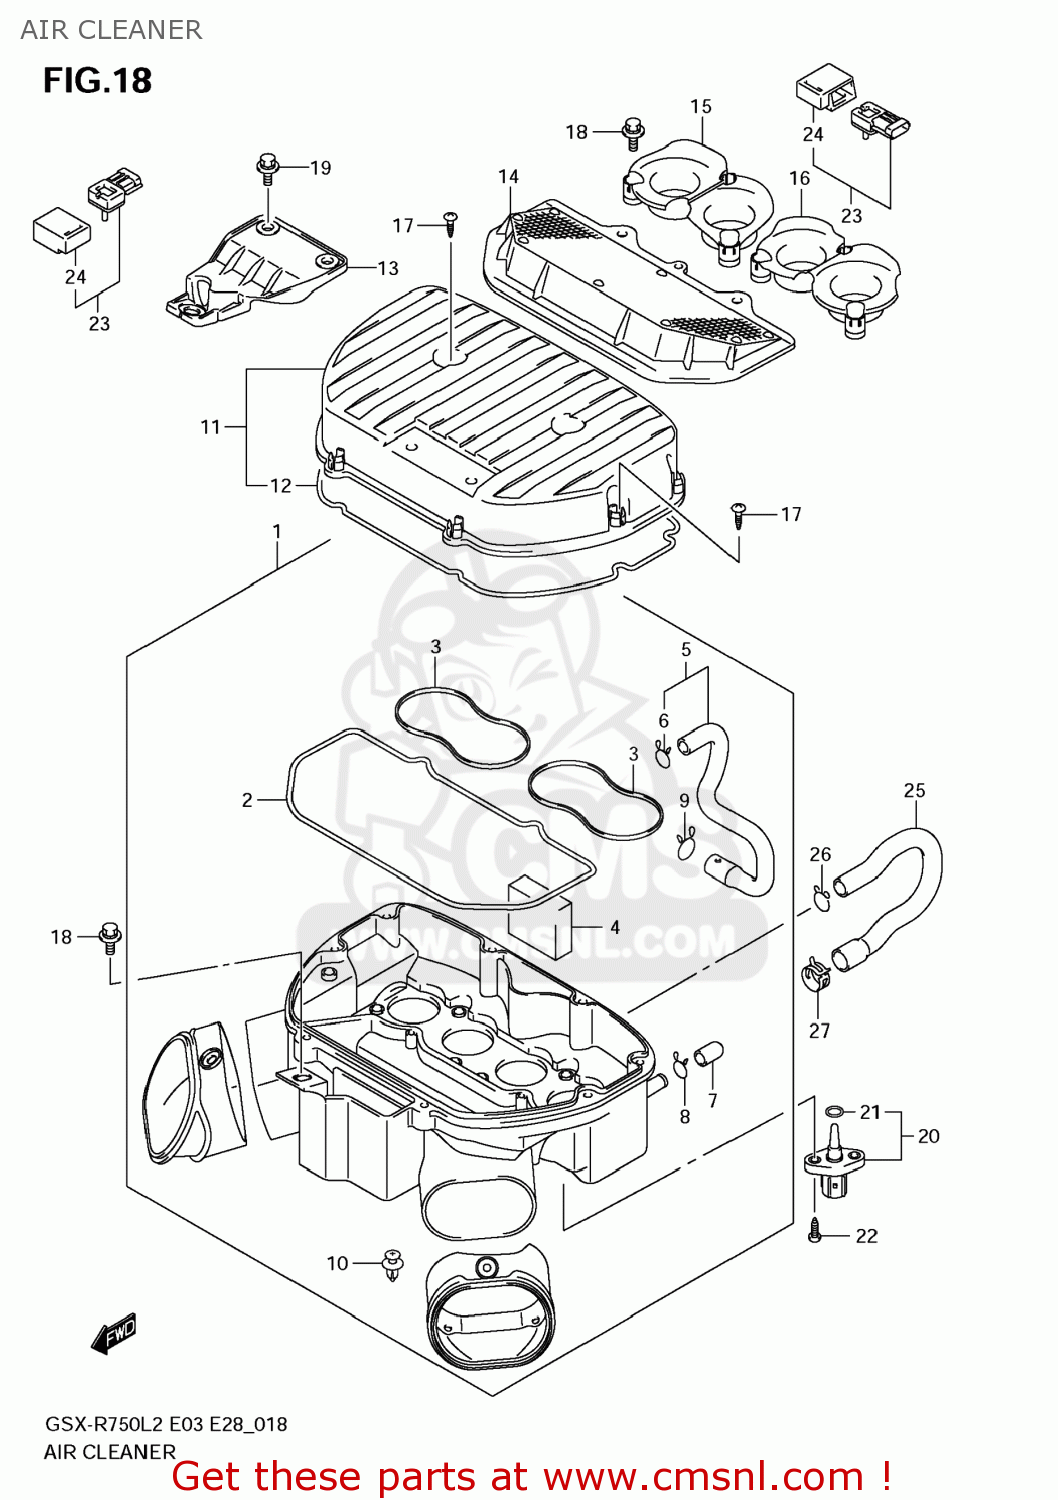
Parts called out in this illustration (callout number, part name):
1	CASE,AIR CLEANER
2	GASKET,CASE (NAS)
3	GASKET,CASE (NAS)
4	FILTER,BREATHER
5	TUBE,BREATHER
6	CLIP
7	PLUG
8	CLIP
9	CLIP
10	CLIP(BLACK)
11	CAP,AIR CLEANER
12	GASKET,CAP (NAS)
13	HOLDER,AIR CLEANER
14	FILTER ASSY
15	FUNNEL,OUTLET,R
16	FUNNEL,OUTLET,L
17	SCREW
18	BOLT,AIR CLEANER CASE
19	BOLT(6X16)
20	SENSOR,AIR TEM
21	O RING
22	SCREW
23	SENSOR,AIR PRESSURE
24	COVER
25	HOSE
26	CLIP
27	CLIP
